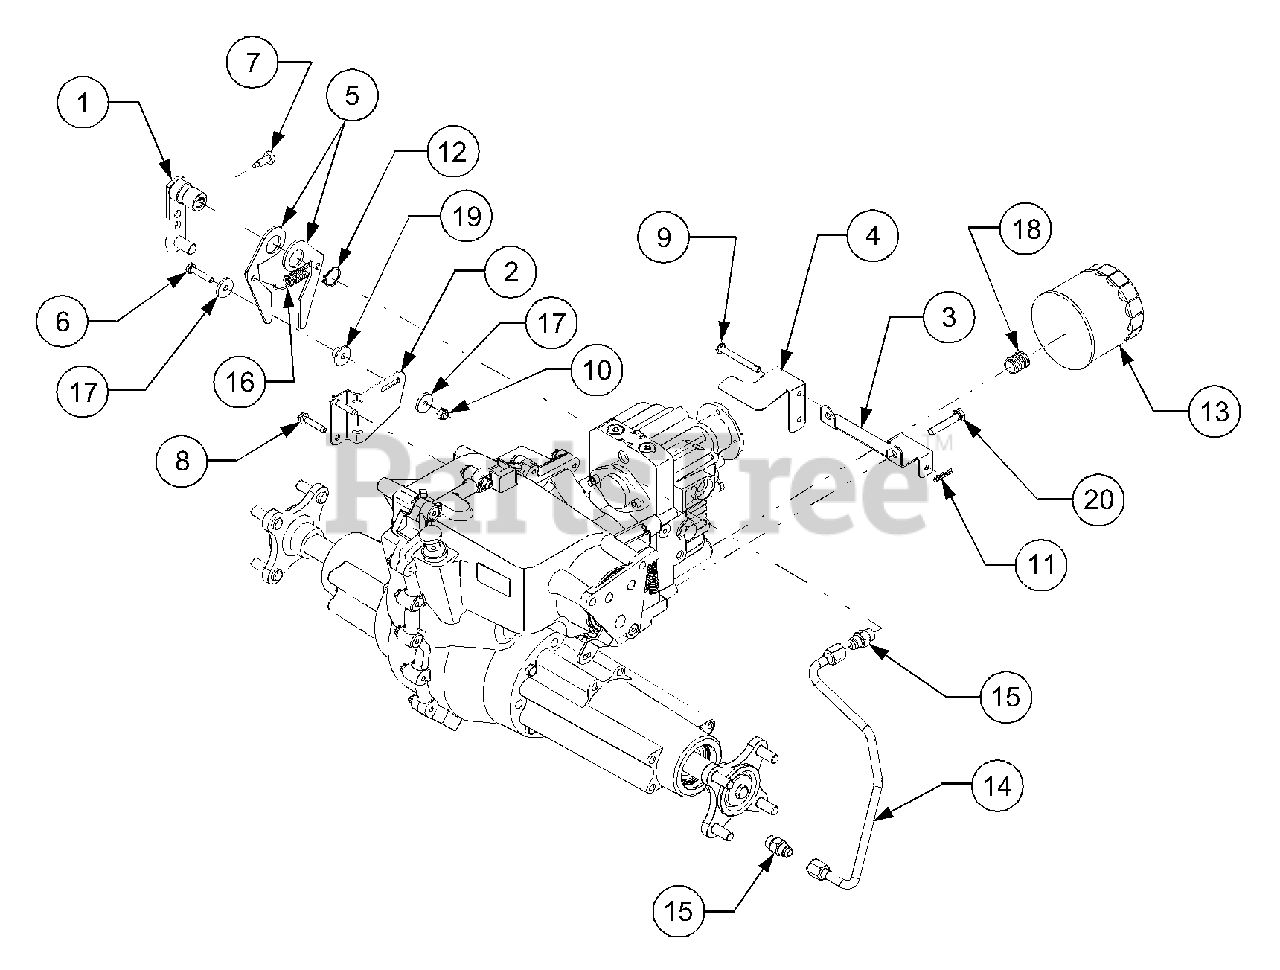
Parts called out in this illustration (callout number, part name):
1	Arm Assembly, Control
2	Bracket, Hydro Neutral
3	Bracket, Hydro Dump Mtg,
4	Bracket, Hydro Dump Actuator
5	Arm, Neutral
6	Screw, Hex Cap, 1/4-20 x 1.25
7	Screw, Special Hex Cap, 5/16-24 x .625
8	Screw, Hex Wash TT-Tap, 1/4-20 x 1.25
9	Pin, Clevis, .25 x 2.38
10	Nut, Hex Top Lock, 1/4-20
11	Pin, Internal Cotter
12	Ring, Snap, .875 Shaft
13	Filter, Oil
14	Tube, Hydro Inlet
15	Connector, w/O-Ring
16	Spring, Extension, .5 OD x 1.97
17	Washer, Flat, .25 x .93 x .120 Thk
18	Nipple, Oil Filter
19	Spacer, Centering
20	Screw, Hex Cap, 5/16-18 x 1.75 GR5
